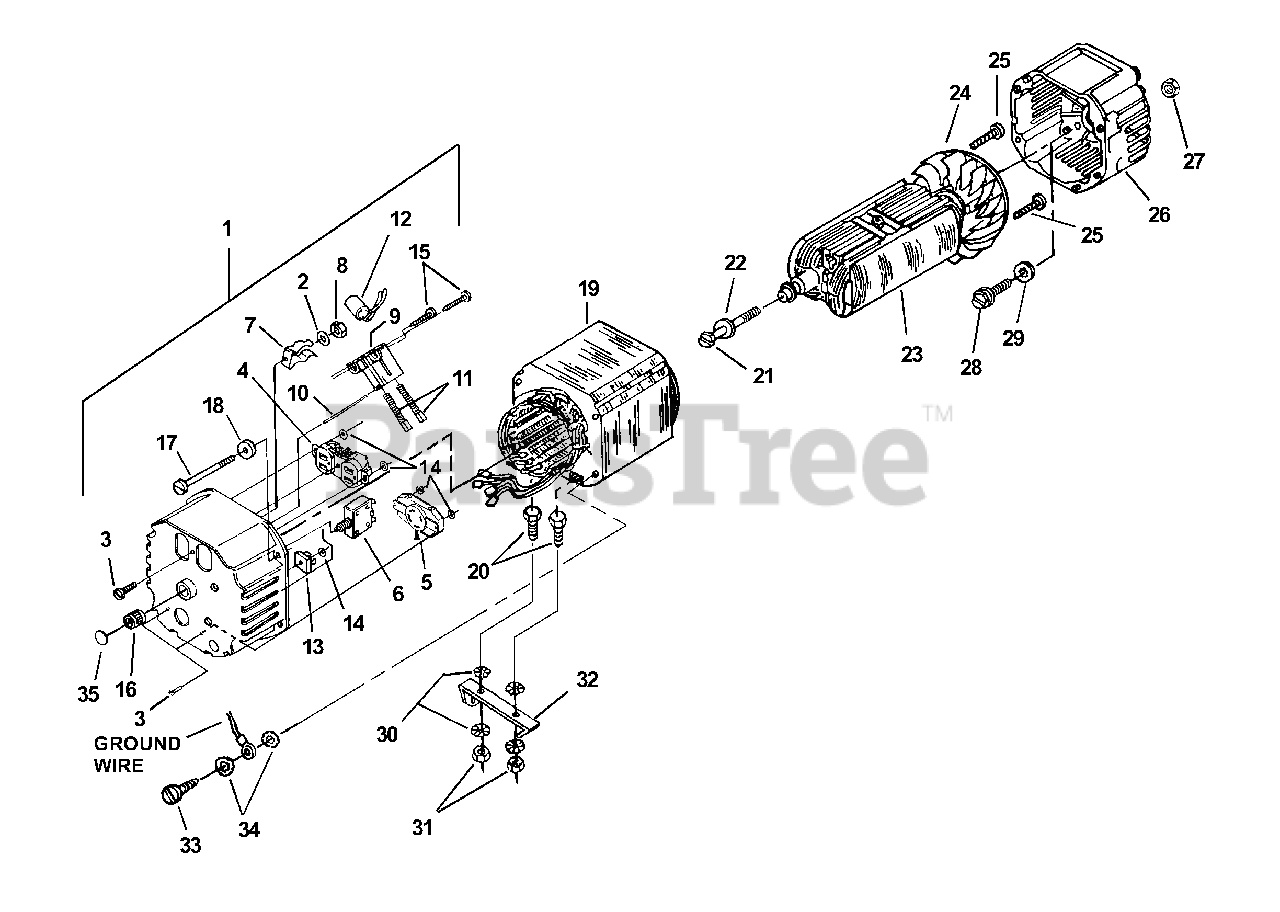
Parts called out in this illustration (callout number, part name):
1	Complete Brush Head
2	Washer-Lock (ext.)
3	Screw-Mach. Pan Hd. (6-32 X 1/2")
4	1A Receptacle-Duplex (Nema 5-20R)
5	Receptacle-Locking (120V/240V) (Nema L14-20R)
6	Breaker-Circuit (20 amp.)
7	Clip-Spring Cap
8	Nut-Hex (6-32)
9	Brush Holder
11	Brush
12	Capacitor (w/Lead)
13	Rectifier
14	Washer-Shaft Retention
15	Screw-Pan Hd. (6-19 X 3/4 )
16	Bearing-Needle
17	Bolt - Stator
18	Washer-Flat
19	Stator
20	Screw- Hex Hd. (5/16-18 X 3/4")
21	Bolt-Rotor
22	Washer-Lock (5/16")
23	AS Rotor
24	Fan-Generator
25	Screw-Pan Hd. (6-19 X 3/4")
26	End Bell
27	Nut-Hex (1/4-20)
28	Screw-Hex Hd. (5/16-24 X 3/4")
29	Washer-Lock
30	Washer-Lock-3/8" (int./ext.)
31	Nut-Hex (5/16-18)
32	Support-Engine
33	Screw-Taptite (10/24 X 3/4")
34	Washer-Lock (int./ext.)
35	Plug-Expansion
